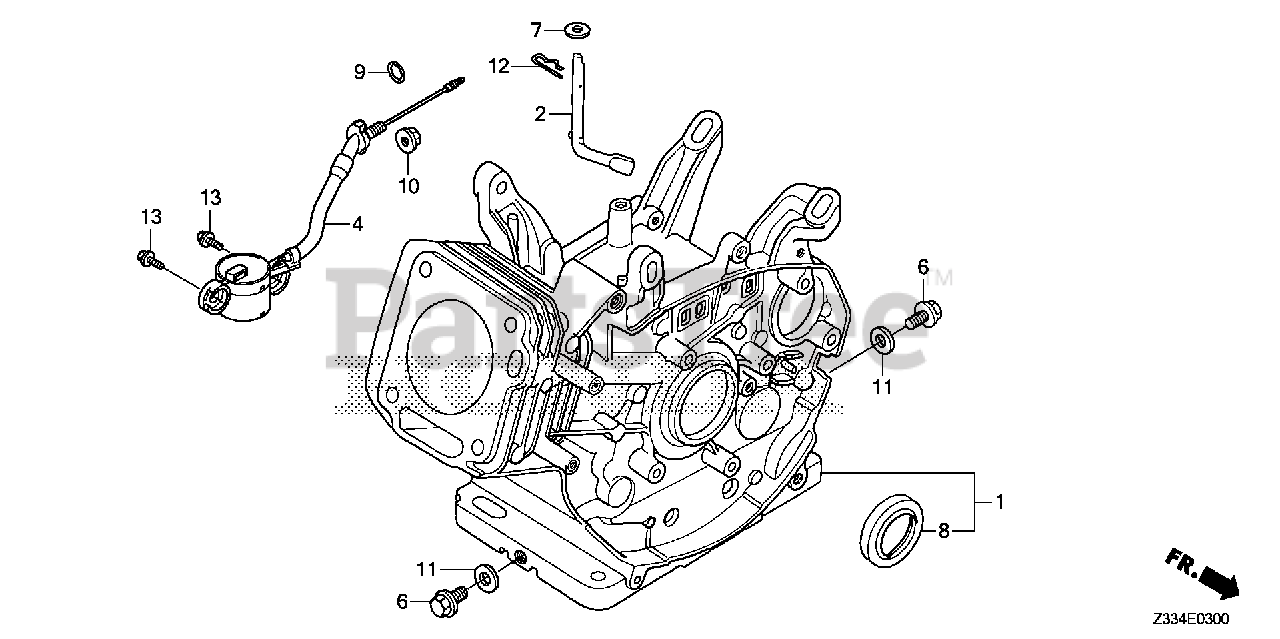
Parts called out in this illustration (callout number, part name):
1	CYLINDER ASSY.
2	SHAFT, GOVERNOR ARM
4	SWITCH ASSY., OIL LEVEL
6	BOLT, DRAIN PLUG
7	WASHER (8.2X17X0.8)
8	OIL SEAL (30X46X8) (NOK ASIA)
8	OIL SEAL (30X46X8)
9	O-RING (14MM) (ARAI) Use up to Engine SN 2949254.
9	O-RING (14MM) (NOK)
10	NUT, FLANGE (10MM)
11	WASHER, DRAIN PLUG (12MM)
12	PIN, LOCK (10MM)
13	BOLT, FLANGE (6X12) Use up to Engine SN 1543277.
